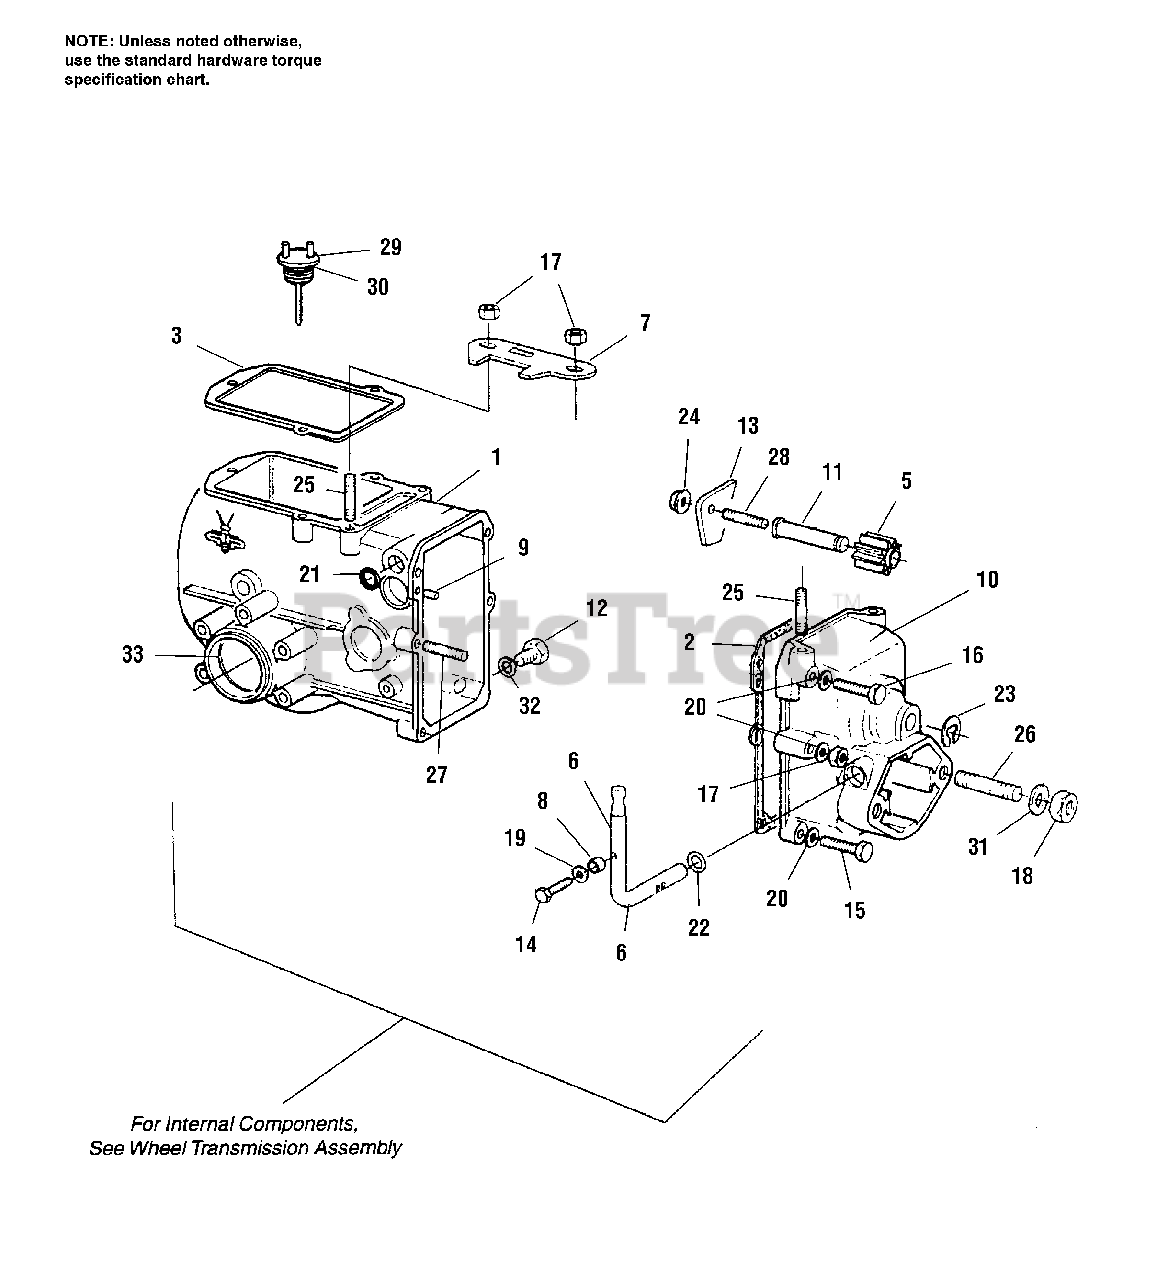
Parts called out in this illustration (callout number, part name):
1	WHEEL DRIVE TRANSMISSION, Bolt-On
2	GASKET-Housing, Front
3	GASKET-Housing, Top
5	GEAR-Reverse Jack Shift
6	ARM-PTO Engage
7	STOP PLATE-Forward/Reverse
9	PIN-Dowel, 6mm x 16mm
10	COVER-Rear Transmission Housing
11	STUB SHAFT, Jack Shift
12	BOLT, Drain Plug
14	BOLT, 6mm x 16mm
15	BOLT, 8mm x 30mm
16	BOLT, 8mm x 45mm
17	NUT, 8mm x 1.25mm
18	NUT, 12mm x 1.25mm
19	WASHER, 6mm
20	WASHER-Wavy, 8mm
21	SEAL-N/1/2 Arm, 12mm x 19mm x 5mm
22	SEAL-PTO Engage Arm
23	SNAP RING-C Clip
24	LOCKNUT, 8mm
25	STUD, 8mm x 20mm
26	STUD, 12mm x 30mm
27	STUD, 8mm x 45mm
29	DIP STICK, Plastic
30	O-RING, Dip Stick
31	WASHER-Flat,12mm
32	WASHER-Nylon, Drain Plug
